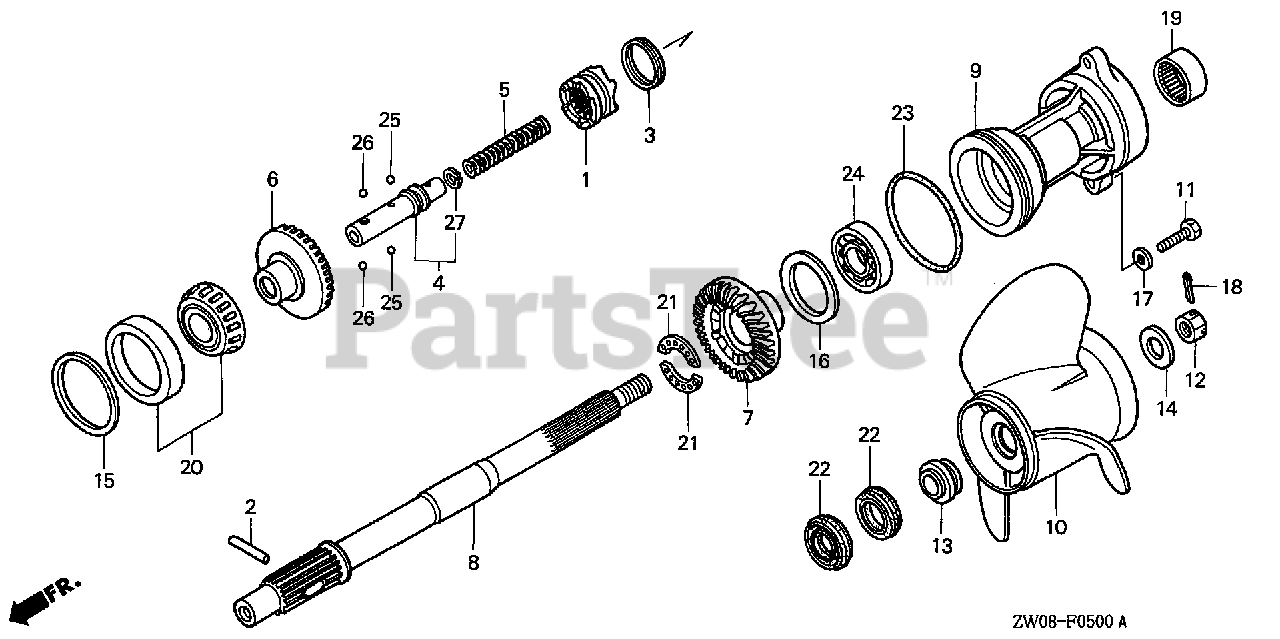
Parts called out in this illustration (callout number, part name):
1	SHIFTER, CLUTCH
2	PIN, SHIFTER (8X47)
3	RING, CROSS PIN
4	SLIDER, SHIFT
5	SPRING, SHIFT
6	GEAR, BEVEL (F)
7	GEAR, BEVEL (R)
8	SHAFT, PROPELLER
9	HOLDER, PROPELLER SHAFT *NH282MU* (OYSTER SILVER METALLIC-U)
10	PROPELLER, THREE-BLADE (14X13) *NH105* (AL) (MAT BLACK) Use up to Frame SN 1302159.
10	PROPELLER, THREE-BLADE (13-3/4X15) *NH105* (AL) (MAT BLACK) Use up to Frame SN 1302159.
10	PROPELLER, THREE-BLADE (13X19) *NH105* (AL) (MAT BLACK) Use up to Frame SN 1302159.
10	PROPELLER, THREE-BLADE (13-1/4X17) *NH105* (AL) (MAT BLACK) Use up to Frame SN 1302159.
10	PROPELLER, THREE-BLADE (13X21) *NH283* (AL) Use from Frame SN 1302160.
10	PROPELLER, THREE-BLADE (13X19) (SUS) Use from Frame SN 1302132.
10	PROPELLER, THREE-BLADE (13X21) (SUS) Use from Frame SN 1302132.
10	PROPELLER, THREE-BLADE (14X11) *NH283* (AL) Use from Frame SN 1302160.
10	PROPELLER, THREE-BLADE (13-3/4X13) *NH283* (AL) Use from Frame SN 1302160.
10	PROPELLER, THREE-BLADE (13-1/4X17) *NH283* (AL) Use from Frame SN 1302160.
10	PROPELLER, THREE-BLADE (13X19) *NH283* (AL) (STIN GRAY)
10	PROPELLER, THREE-BLADE (13-1/4X17) (SUS) Use from Frame SN 1302160.
10	PROPELLER, THREE-BLADE (13-1/2X15) *NH283* (AL) (STIN GRAY)
11	BOLT, HEX. (10X40)
12	NUT, CASTLE (18MM)
13	WASHER, PROPELLER THRUST
14	WASHER, PLAIN (18.5MM)
15	SHIM A, BEVEL (0.10) (FR.)
15	SHIM B, BEVEL (0.15) (FR.)
15	SHIM C, BEVEL (0.30) (FR.)
15	SHIM D, BEVEL (0.50) (FR.)
16	SHIM A, BEVEL GEAR (0.10) (RR)
16	SHIM B, BEVEL GEAR (0.15) (RR)
16	SHIM C, BEVEL GEAR (0.30) (RR)
16	SHIM D, BEVEL GEAR (0.50) (RR)
17	WASHER, PLAIN (10MM)
18	PIN, SPLIT (4.0)
19	BEARING, NEEDLE (30X37X26)
20	BEARING, TAPERED ROLLER (50X82X21.5)
21	BEARING, BALL (28X38X3)
22	SEAL, WATER (30X45X7)
23	O-RING (94X4.1)
24	BEARING, RADIAL BALL (6208)
25	BALL, STEEL (#6) (3/16)
26	BALL, STEEL (#11) (11/32)
27	CIRCLIP (OUTER) (14MM)
